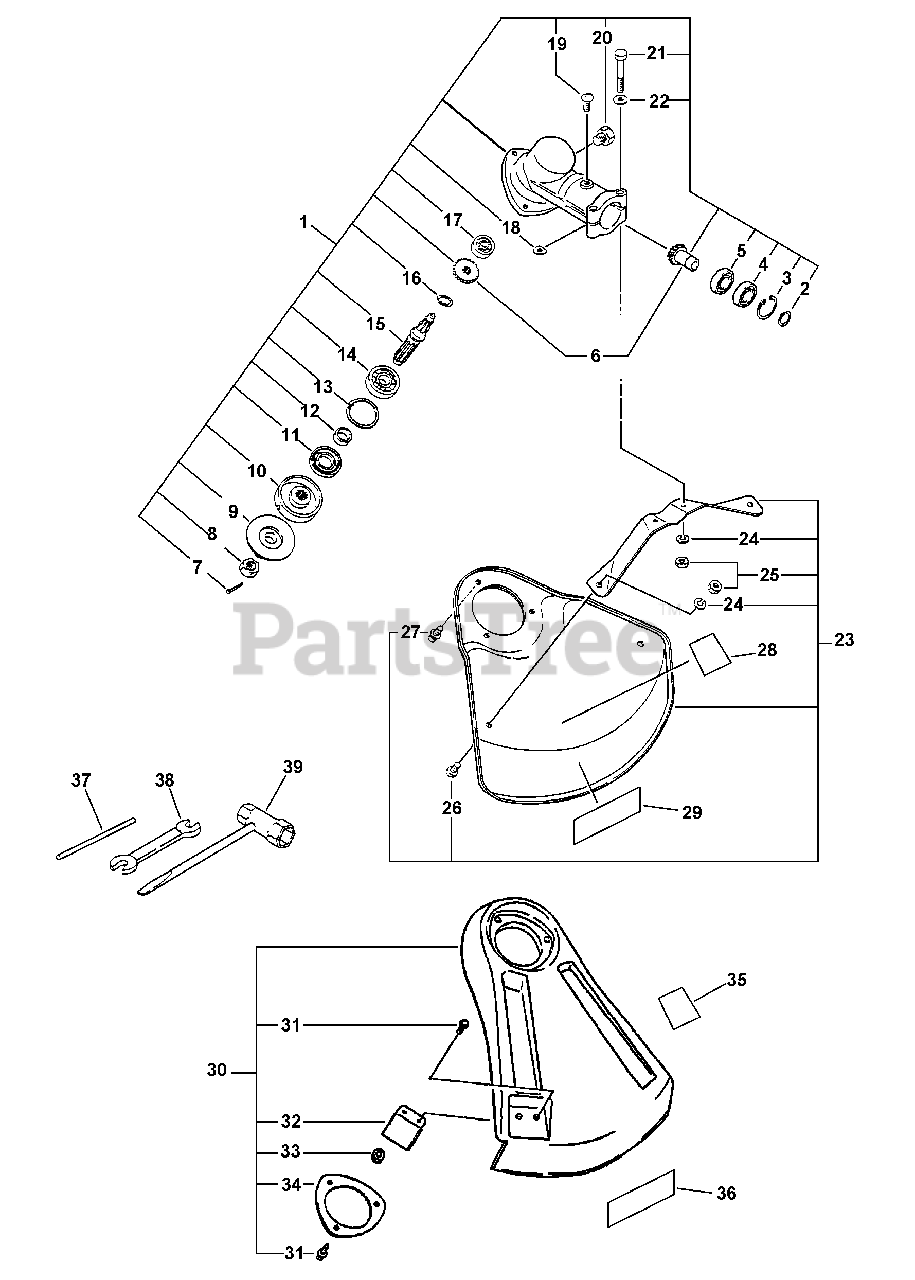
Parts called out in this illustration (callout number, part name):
1	Gear Housing Asy
2	Circlip 10
3	Circlip 22
4	Bearing, Ball 6900
5	Bearing, Ball 6900
6	Gear Set, Bevel
7	Pin, Split 2x22
8	Nut 10 - Left Handed
9	Plate, Adapter - Lower
10	Plate, Adapter - Upper
11	Seal, Oil
13	Circlip 32
14	Bearing, Ball 6201
15	Shaft, p.t.o.
16	Circlip 12
17	Bearing, Ball 609
18	Washer, Shim
19	Screw 5x10
20	Bolt 8x6
21	Bolt 5x35
22	Washer 5
23	Shield Asy
24	Washer, Spring 5
26	Screw 5x8
27	Screw 5x10
28	Label, Echo
28	Label, Caution
30	Shield Asy
31	Screw 5x16
32	Knife, Cord
34	Bracket, Shield
35	Label, Caution
36	Label, Echo
37	Locking Tool
38	Spanner 8x10
39	Wrench, W/Screwdriver
